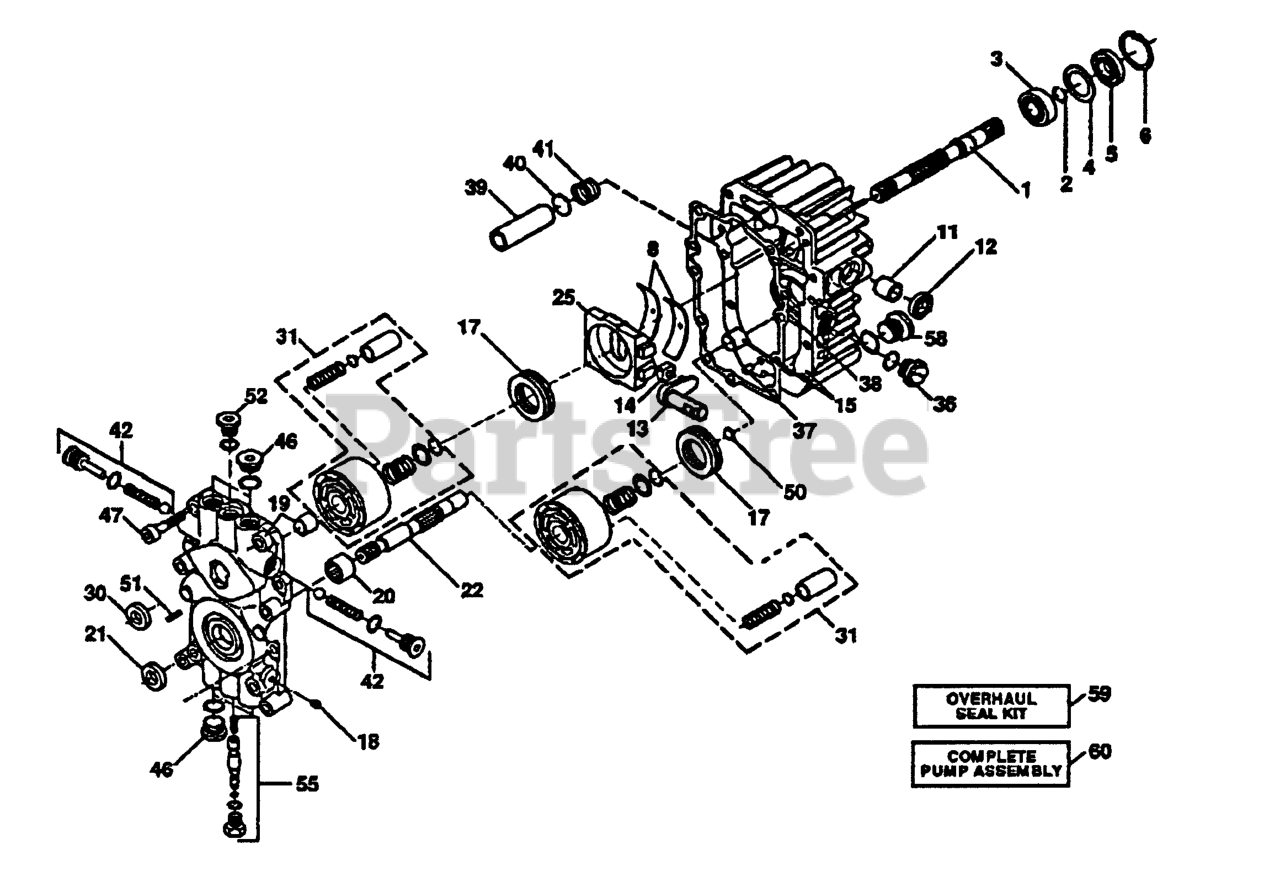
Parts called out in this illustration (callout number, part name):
1	SHAFT 2003022
2	RETAINIANG RING
3	BALL BEARING 2003043
4	SPACER
5	SEAL LIP
6	RETAINING PIN
8	CRADLE BEARING
12	SEAL LIP
13	TRUNION ARM
14	GUIDE 2000015 HYD
15	PUMP ASM COMP
17	BALL BEARING
19	KIT,CTR SECTION
20	NEEDLE BEARING
21	LIP SEAL 9008000-0127
25	SWASHPLATE,VARIAB
30	SEAL LIP
31	KIT,BLOCK CYLINDE
36	PLUG,PLASTIC
38	GASKET 2003060
39	FILTER 2003003
42	KIT,CHECK VALVE 2513014
55	KIT,BYPASS VALVE(2513011)
59	KIT,OVERHEAD SEAL -2513013
60	Pump Assembly, Complete
